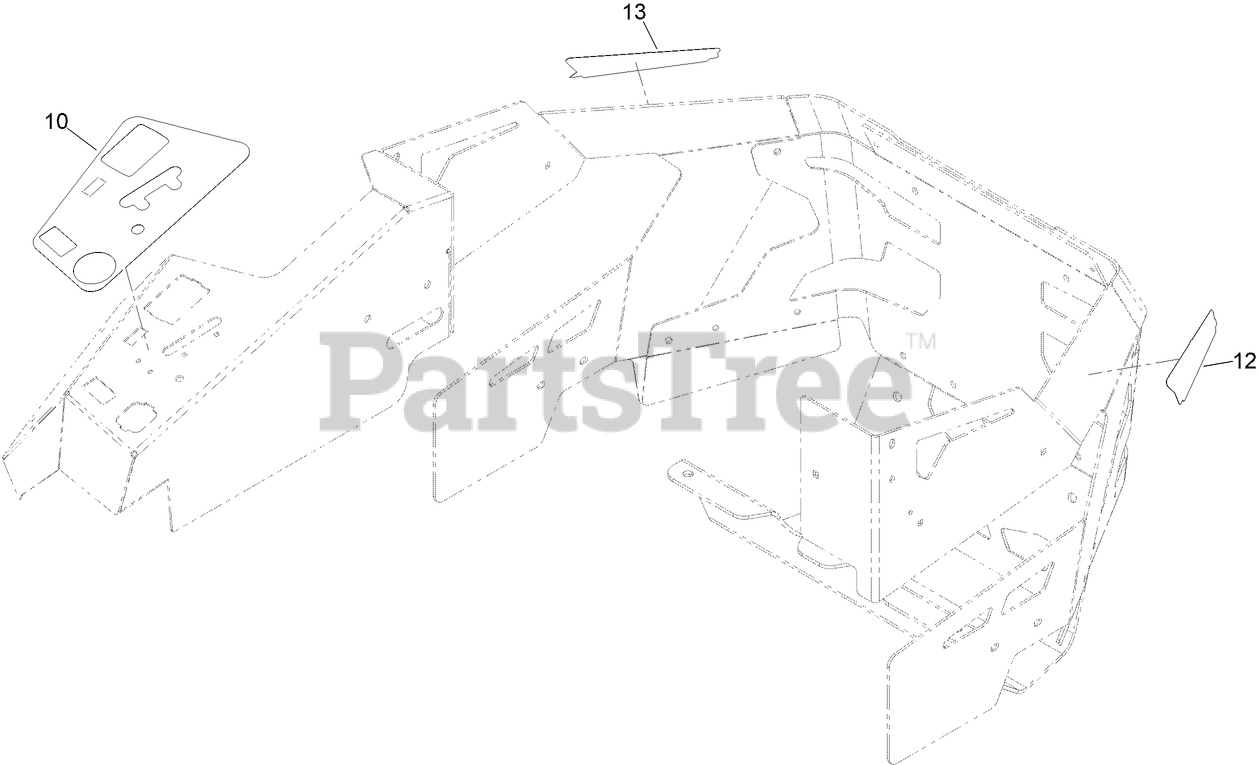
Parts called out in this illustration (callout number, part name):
10	DECAL-PANEL, CONTROL
12	DECAL-HDX PRO XL
13	DECAL-HDX PRO XL
